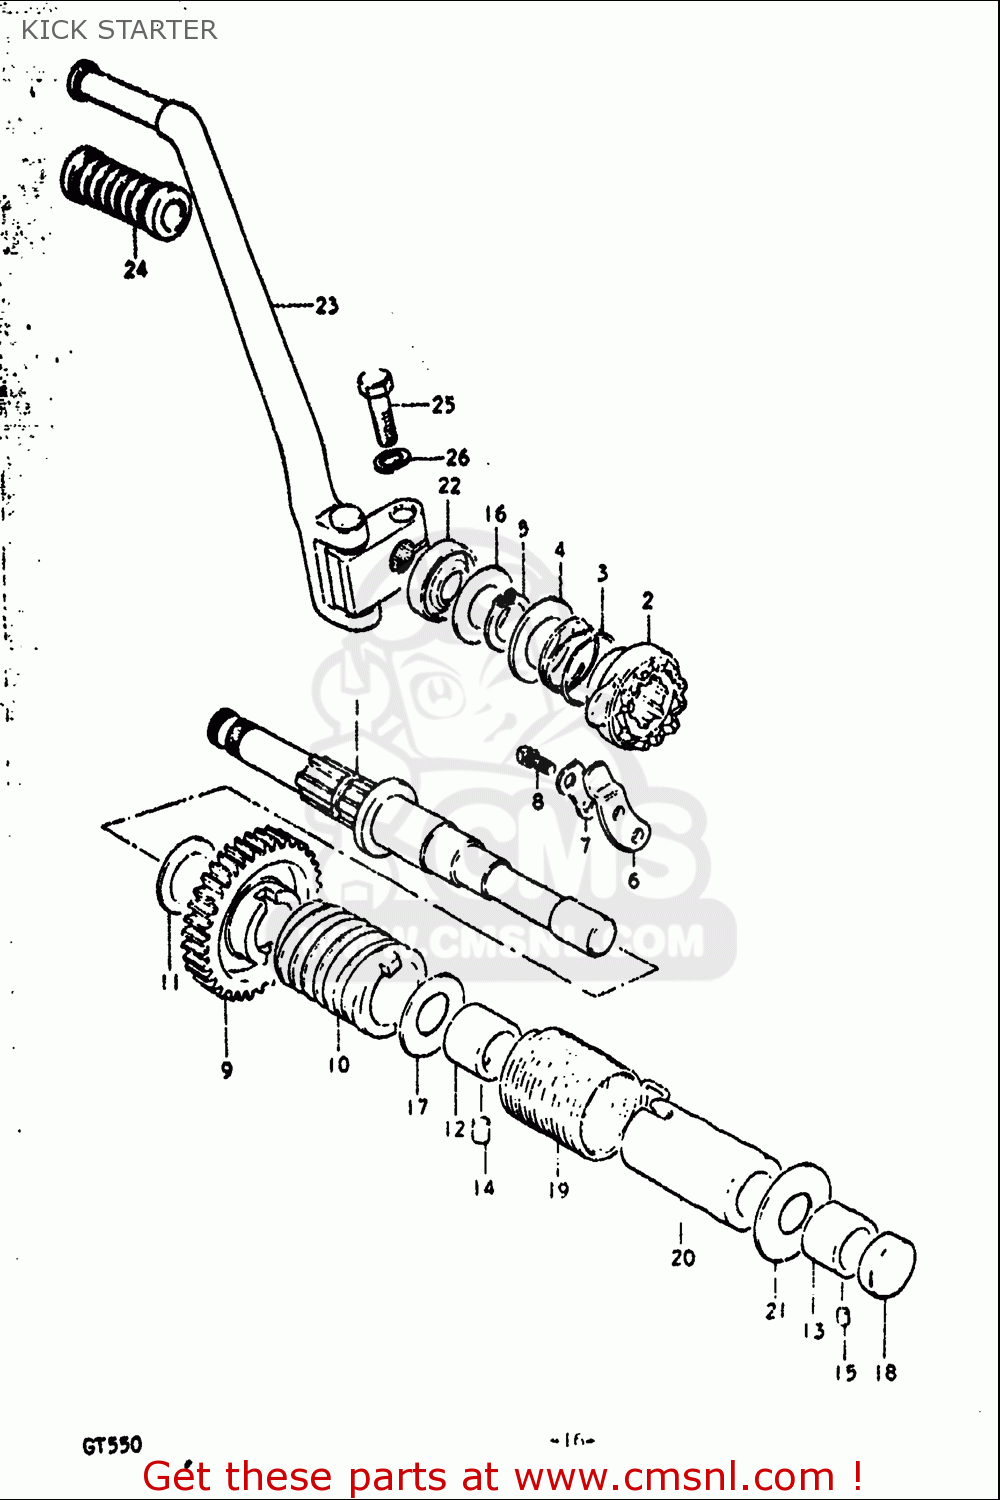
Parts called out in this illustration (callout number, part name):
2	STARTER,KICK
3	SPRING
5	CIRCLIP
8	BOLT
11	SHIM(20X28X1)
14	PIN
15	PIN
16	THRUST WASHER
17	WASHER
18	PLUG
19	SPRING
22	SEAL,OIL(16X30X8)
24	RUBBER,KICK STARTER PEDAL
25	BOLT
26	WASHER,LOCK
